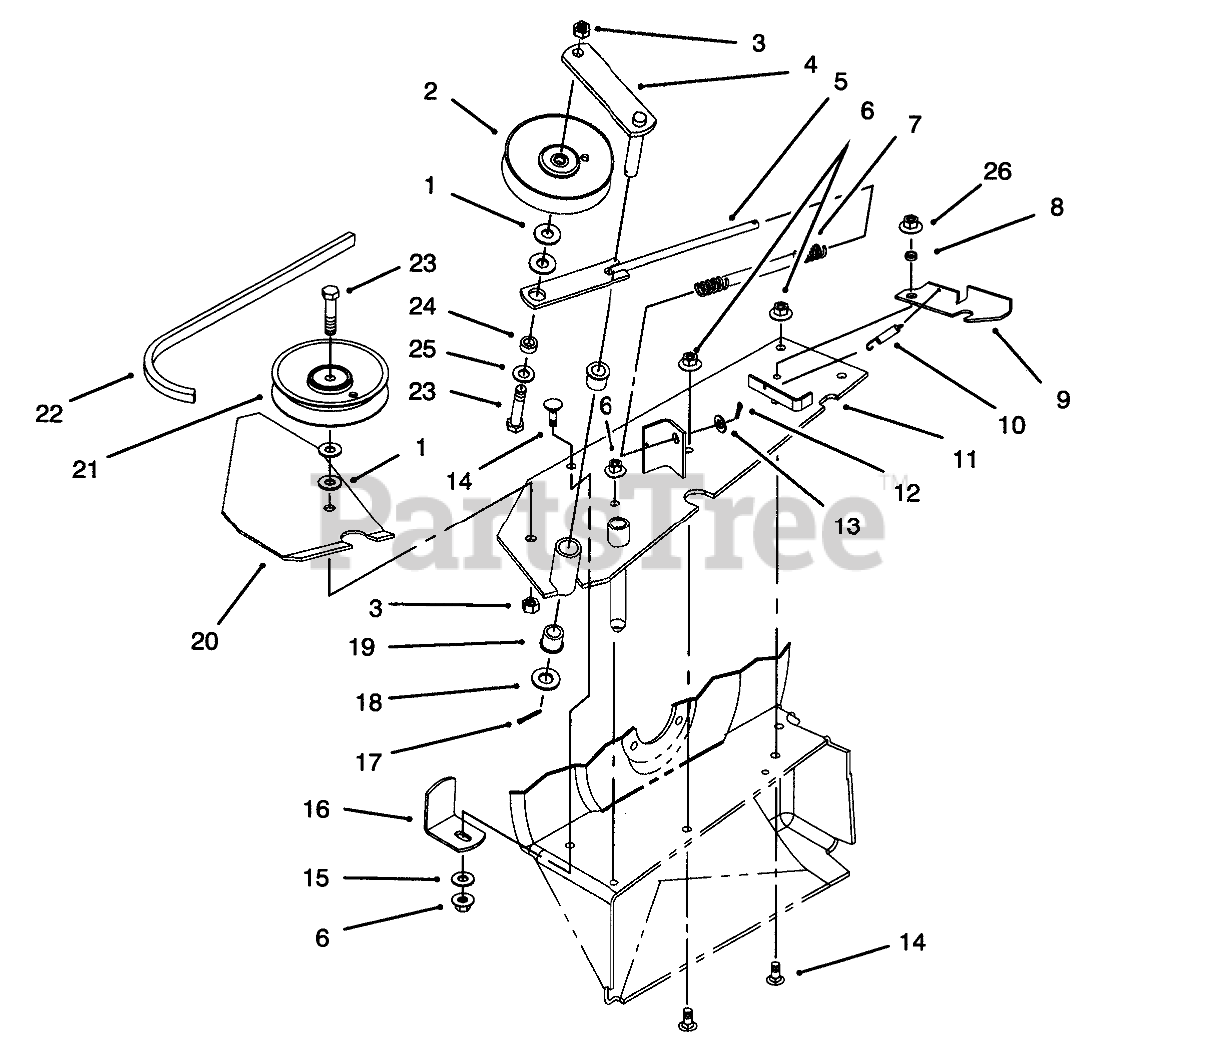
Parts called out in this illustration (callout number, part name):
1	WASHER-FLAT
2	PULLEY-IDLER
3	NUT-LOCK, NI
4	IDLER ARM ASM
5	SPRING-ROD
6	NUT-HF
7	SPRING-COMPRESSION
8	BUSHING
9	LATCH - BLOWER B
10	SPRING-EXTENSION
11	BLOWER MOUNTING-WELDED B
12	PIN-COTTER
13	WASHER-PLAIN
14	SCREW-CARR
15	WASHER-FLAT
16	BRACKET-SUPPORT, HOUSING
17	PIN-COTTER
18	WASHER-FLAT
19	BUSHING
20	SHIELD SUPPORT B
21	PULLEY-IDLER
22	BELT-V
23	SCREW-HH
24	SPACER
25	WASHER-FLAT
26	NUT-LOCK, NI
